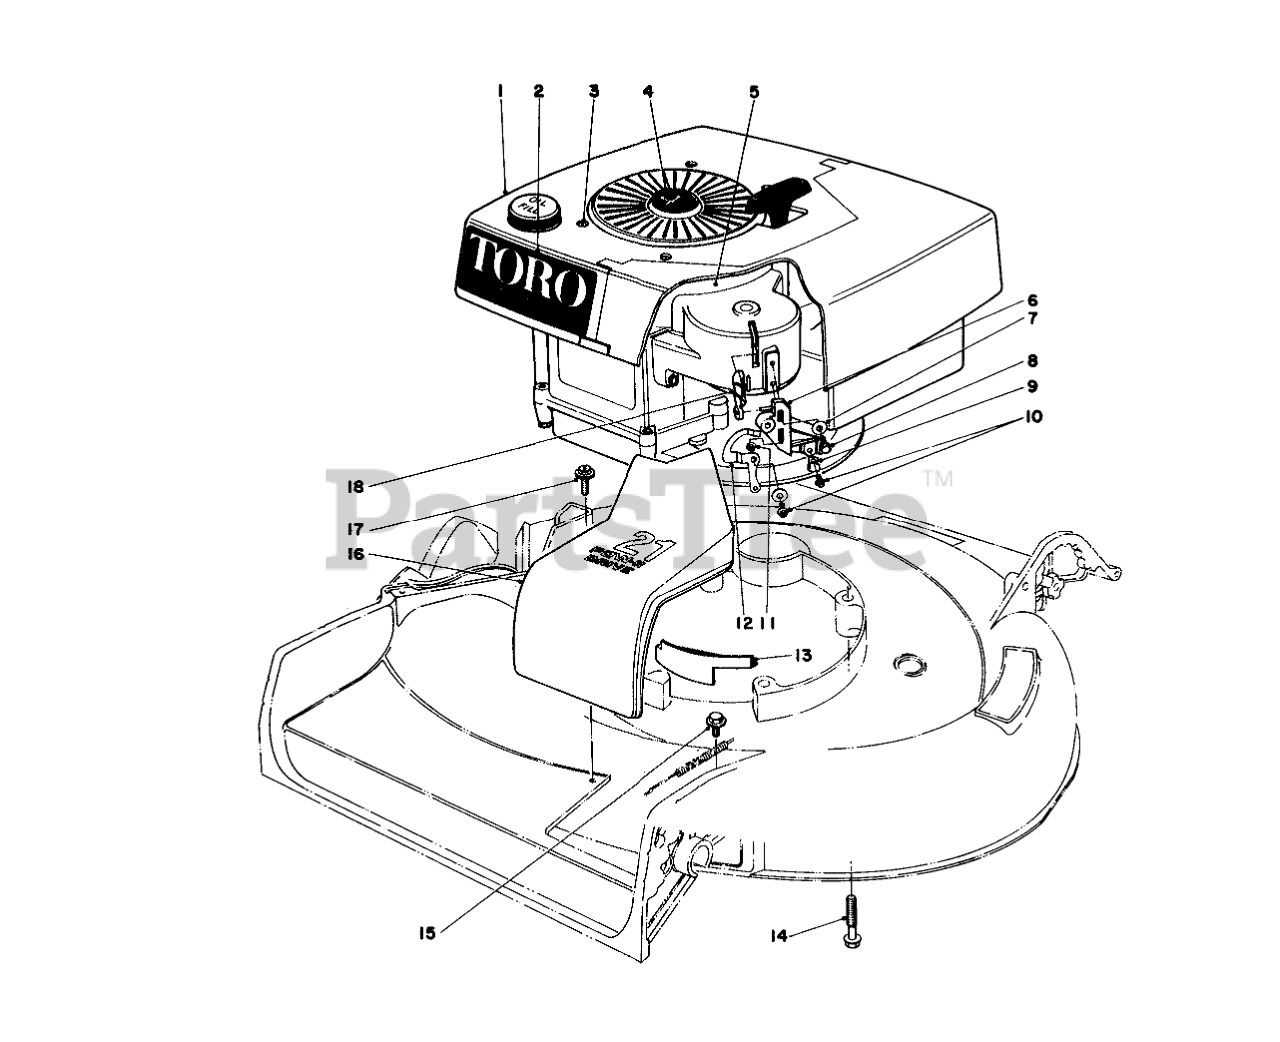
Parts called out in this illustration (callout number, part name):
1	SHROUD
2	Decal
3	8X1/2 SELF TAP SCREW
4	Decal-Shroud
5	Engine
6	CABLE & PIVOT BLOCK
7	WASHER-FLAT
8	SCREW-SHWH
9	CLAMP
10	SCREW-HWHTF
11	BUSHING
12	CAM INTERLOCK
13	HOUSING CAP
14	3/8-16 X 2-3/4 CAPSCR
15	SCREW-HWHTF
16	Cover Belt Drive
17	SCREW
18	INTERLOCK LEVER
